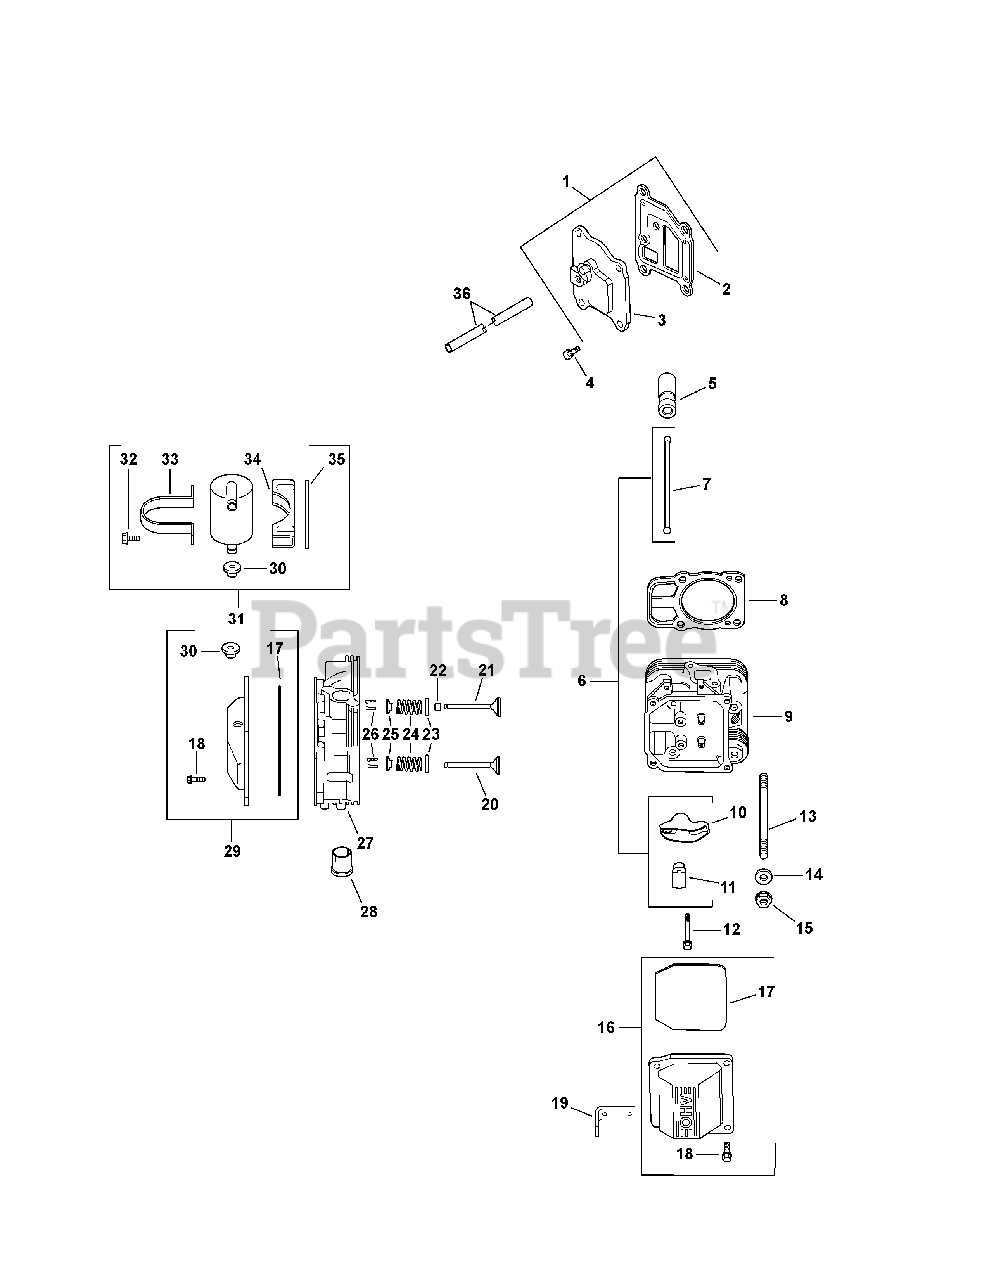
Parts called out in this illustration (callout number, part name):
1	KIT, BREATHER COVER W/GASKET
2	GASKET, BREATHER
3	KIT, BREATHER COVER
4	SCREW, FLG THD FRM M6X1.0X20
5	LIFTER, VALVE HYDRAULIC
6	KIT, VALVE TRAIN
8	KIT, CYL HEAD GASKET(C730-745)
9	HEAD KIT, CYL #2
11	PIVOT, ROCKER ARM
12	SCREW, FLG M6X1.0X34
13	STUD, M8X1.25
14	WASHER, FLAT 8.6 MM
15	NUT, FLG M8X1.25
16	KIT, VALVE COVER-PLAIN
17	O-RING, VALVE COVER
18	SCREW, FLG M6X1.0X30 M6x1.0x30
19	STRAP, LIFTING
20	VALVE, EXHAUST (STD)
20	VALVE, EXHAUST (.25)
21	VALVE, INTAKE (STD)
21	VALVE, INTAKE (.25)
22	SEAL, VALVE STEM
23	RETAINER, SPRING
24	SPRING, VALVE
25	CAP, VALVE SPRING
26	KIT, RETAINER
27	HEAD KIT, CYL #1
29	KIT, VALVE COVER
30	GROMMET, RUBBER
31	KIT, BREATHER SEPARATOR
32	SCREW, FLG THD FRM M6X1.0X16
33	STRAP, BREATHER
34	BRACKET, BREATHER SEPARATOR
